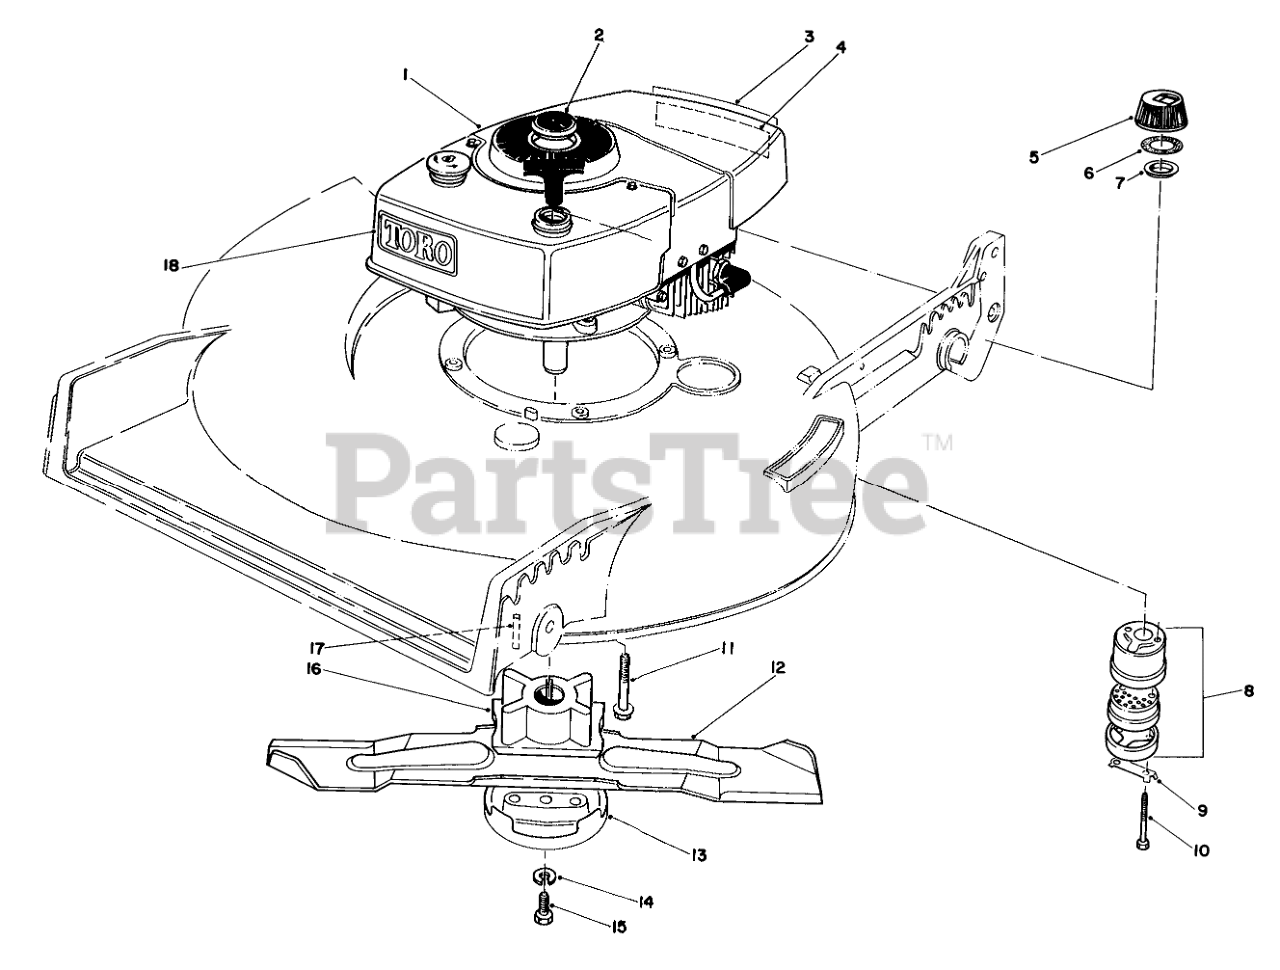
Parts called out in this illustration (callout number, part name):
1	Engine
2	Plug Button
3	Decal-Primer
4	Decal Maintenance
5	Gas Cap Assembly (Incl. Ref. #6 & 7)
6	GASKET
7	GAS CAP BAFFLE
8	Muffler Assembly (Incl. Ref. #9 & 10)
9	CLIP - LOCKING
10	SCREW-HH
11	SCREW-HWHTF
12	BLADE-21in
13	Anti Scalp Cup
14	WASHER-LOCK
15	SCREW-BLADE
16	BLADE RETAINER(DEEP)
17	KEY-SQUARE
18	Decal Tow
